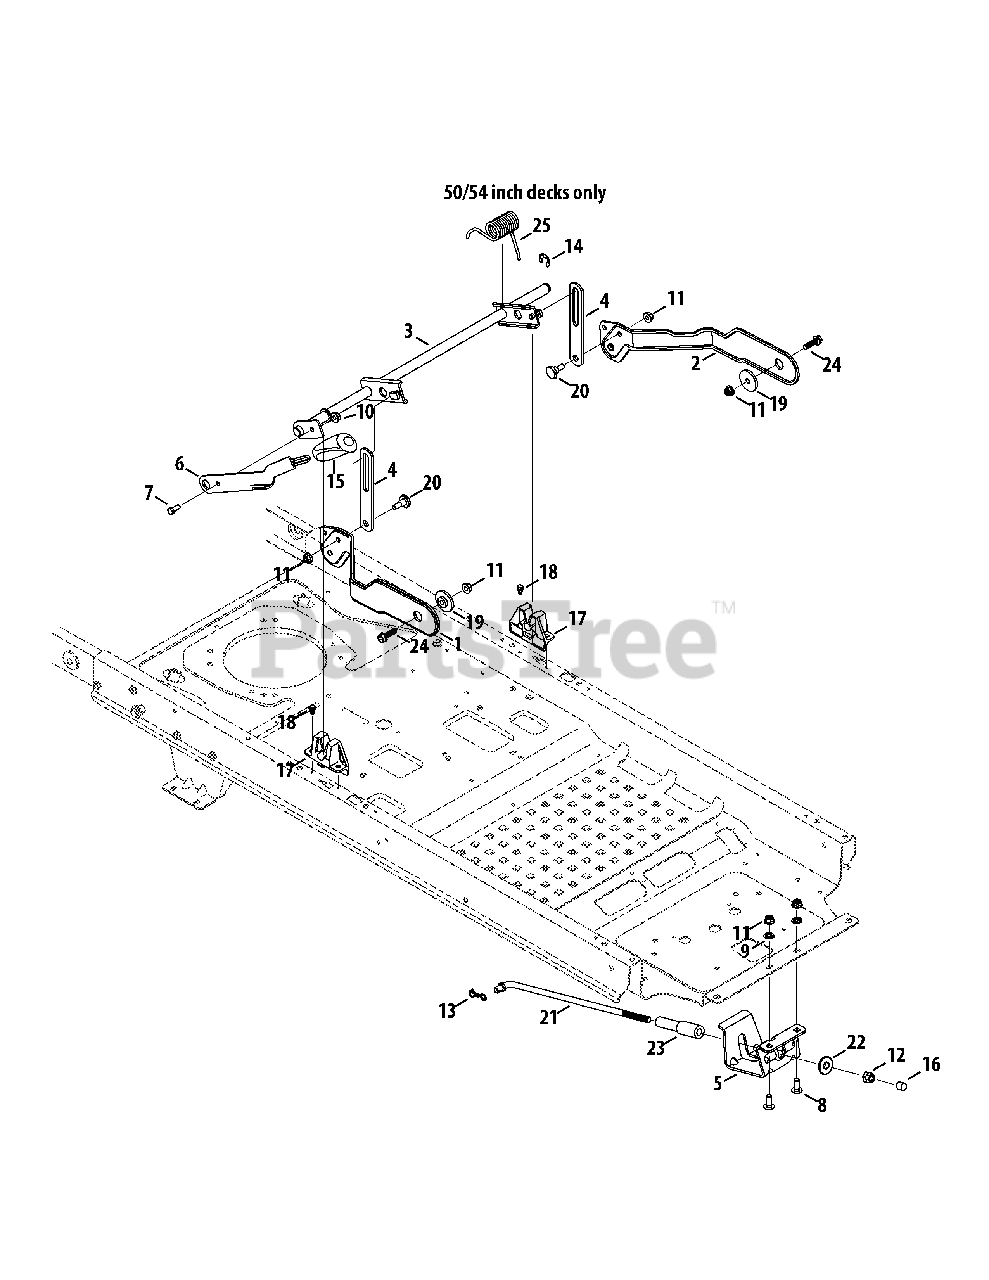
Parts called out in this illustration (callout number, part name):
1	Deck Lift Plate, RH
2	Deck Lift Plate, LH
3	Deck Lift Shift Assembly
4	Lift Link Plate
5	Rod Support Mounting Bracket
6	Deck Lift Handle
7	Hex Cap Screw, 5/16-18 x .75
8	Carriage Bolt, 3/8-16 x 1.00
9	Push Nut, 3/8
10	Flange Lock Nut, 5/16-18
11	Flange Lock Nut, 3/8-16
12	Hex Nut, 1/2-13
13	Bow-Tie Cotter Pin
14	E-Type Ring, .750
15	Grip, .50 ID
17	Deck Lift Bracket
18	Shoulder Screw, .500 x 1/4-20
19	Shoulder Spacer, .854 x .232
20	Shoulder Screw, .500 Dia. x .434
21	Deck Lift Rod
22	Deck Lift pivot Cup
23	Nylon Sleeve, .55 ID x 4.50 LG
24	Screw, 3/8-16 x 1.00
25	Torsion Spring, 1.323 ID x 2.83 LG
